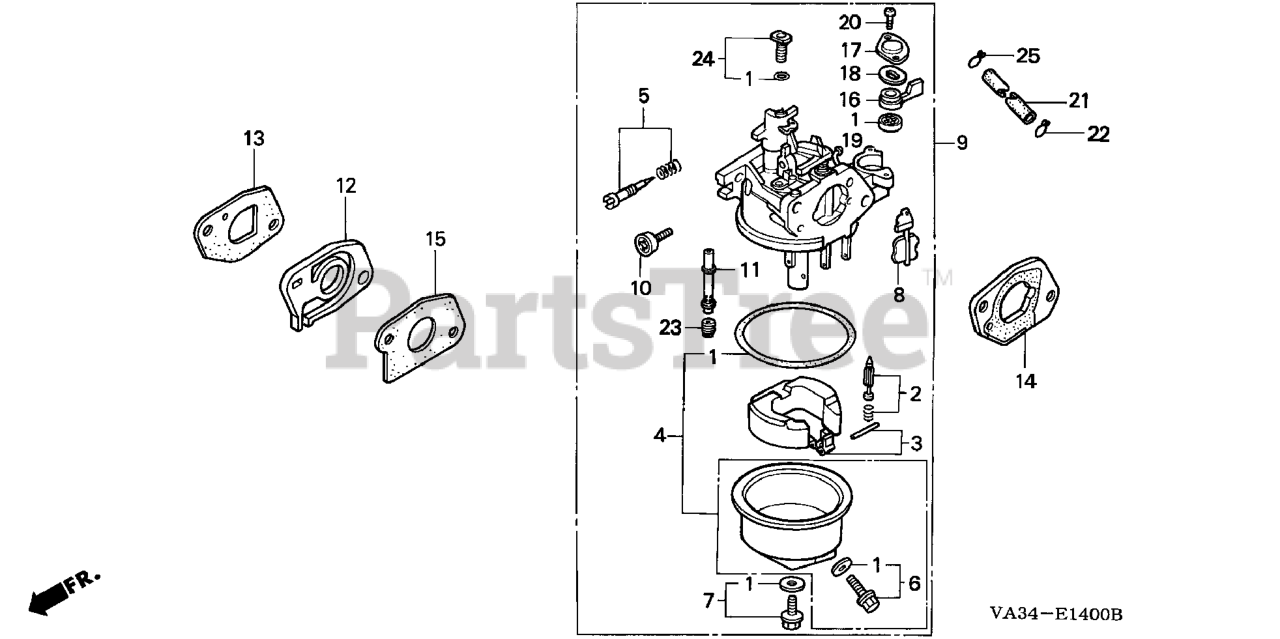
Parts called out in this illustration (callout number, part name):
1	GASKET SET (CARBURETOR NO.)
2	VALVE SET, FLOAT (CARBURETOR NO.) (SEAT NOT INCLUDED)
3	FLOAT SET
4	CHAMBER SET, FLOAT (CARBURETOR NO.)
5	SCREW SET, PILOT (Honda Code 1441500). (CARBURETOR NO.)
6	SCREW SET, DRAIN (Honda Code 1672187). (CARBURETOR NO.)
7	SCREW SET
8	CHOKE SET (CARBURETOR NO.)
9	CARBURETOR ASSY. (BE46A C)
10	SCREW, THROTTLE STOP
11	NOZZLE, MAIN
12	INSULATOR, CARBURETOR
13	GASKET, CARBURETOR (HPE)
14	SPACER, CARBURETOR
15	GASKET, CARBURETOR
16	LEVER, PETCOCK (CARBURETOR NO.)
17	PLATE, LEVER SETTING (CARBURETOR NO.)
18	SPRING, PETCOCK LEVER (CARBURETOR NO.)
19	GASKET, VALVE
20	SCREW, PAN (3X6)
20	SCREW, PAN (3X8) (CARBURETOR NO.)
23	JET, MAIN (#65) Use from Engine SN BE40A G.
23	JET, MAIN (#60) (Honda Code 0635474). (CARBURETOR NO.)
23	JET, MAIN (#62) (Honda Code 0635482). (CARBURETOR NO.)
24	JET SET, PILOT (#35)
